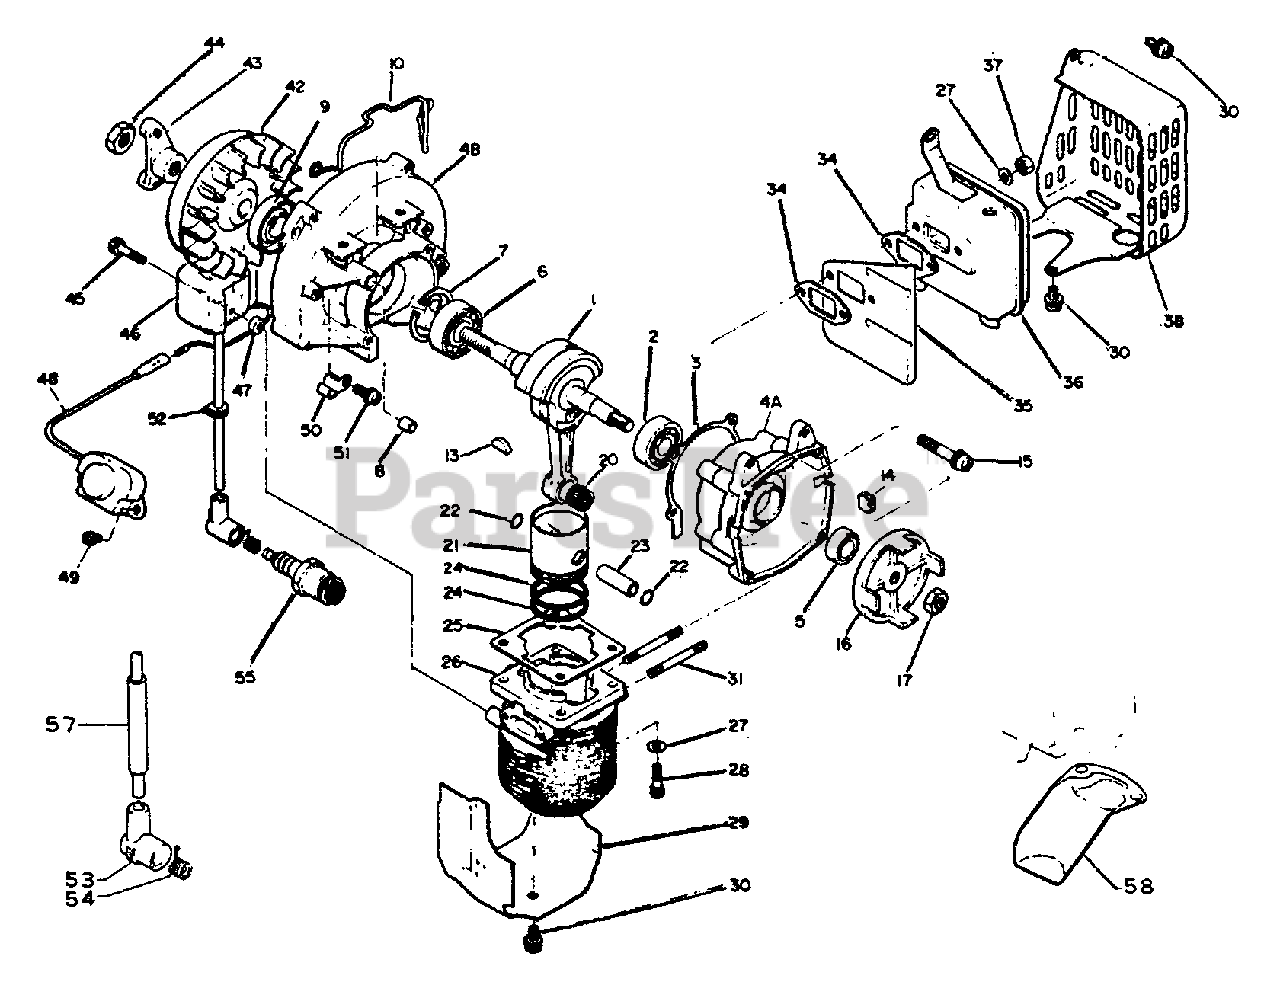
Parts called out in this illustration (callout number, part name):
1	CRANKSHAFT ASSY
2	BEARING, BALL - 6201
3	GASKET, CRANKCASE
5	SEAL, OIL
6	BEARING, BALL - 6202
7	RING, RETAINING - 35
8	PIN - LOCATING
9	SEAL, OIL
10	BUMPER
14	PLUG
15	SCREW - 5X35
16	CATCHER, PAWL
20	BEARING, NEEDLE
21	PISTON
22	RING, RETAINING - 8
23	PIN, PISTON
24	RING, PISTON
25	GASKET, CYLINDER
26	CYLINDER
27	WASHER - 5
28	SCREW - 5X20
29	SHIELD, CYLINDER
30	SCREW - 5X10
31	STUD
34	GASKET, EXHAUST
35	COVER, MUFFLER
36	MUFFLER
37	LOCKNUT - 5
38	COVER, MUFFLER
42	FLYWHEEL
43	HUB, CLUTCH
44	NUT - 10
45	SCREW - 5X22
46	COIL, IGNITION
47	SPACER
48	COIL, IGNITION
49	SCREW - 5X6
50	CLAMP
51	SCREW - 5X12
53	CAP, SPARK PLUG
54	TERMINAL, SPARK PLUG CAP
55	SPARK PLUG -- BM-6A
57	TUBE
